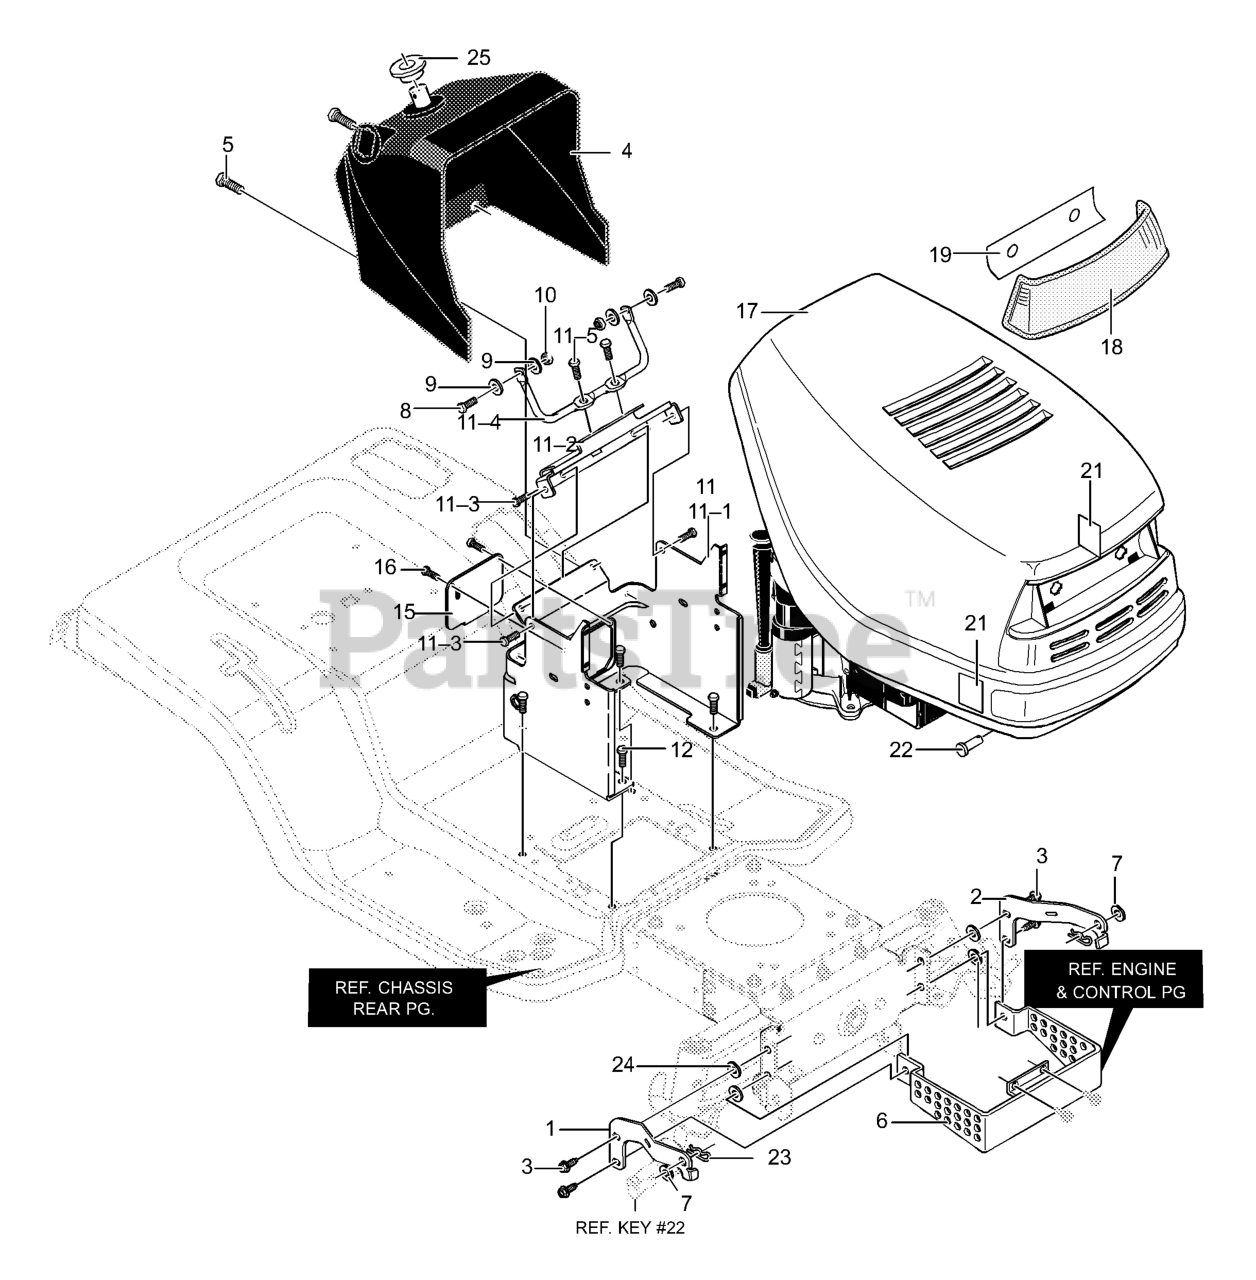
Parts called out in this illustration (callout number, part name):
1	Bracket, Hood RH
2	Bracket, Hood LH
3	Screw, 5/16-18 x 0.75
5	Screw, 1/4-14x.75
6	Heat Shield Guard
7	Washer, Flat Insulate
8	Screw, 1/4-20x.75
9	Washer, Flat .286x.63x.065
10	Nut, 1/4-20 Reghexctrlk
11	Assembly, Lower Console
11-1	Tower, Lower Dash
11-2	Support, Steering
11-3	Screw, 1/4-20x.50
11-4	Rod, Dash Brace
11-5	Screw, 1/4-20x.50
12	Screw, 10-24x.50
15	Panel, Access
16	Screw, 10-24x.50
18	Lens, Headlamp
19	Foil, Lens
21	Foil, Heat Reflector
22	Pin, Clevis
23	Hair Pin
24	Washer, Flat
25	Bushing, Steering Shaft
